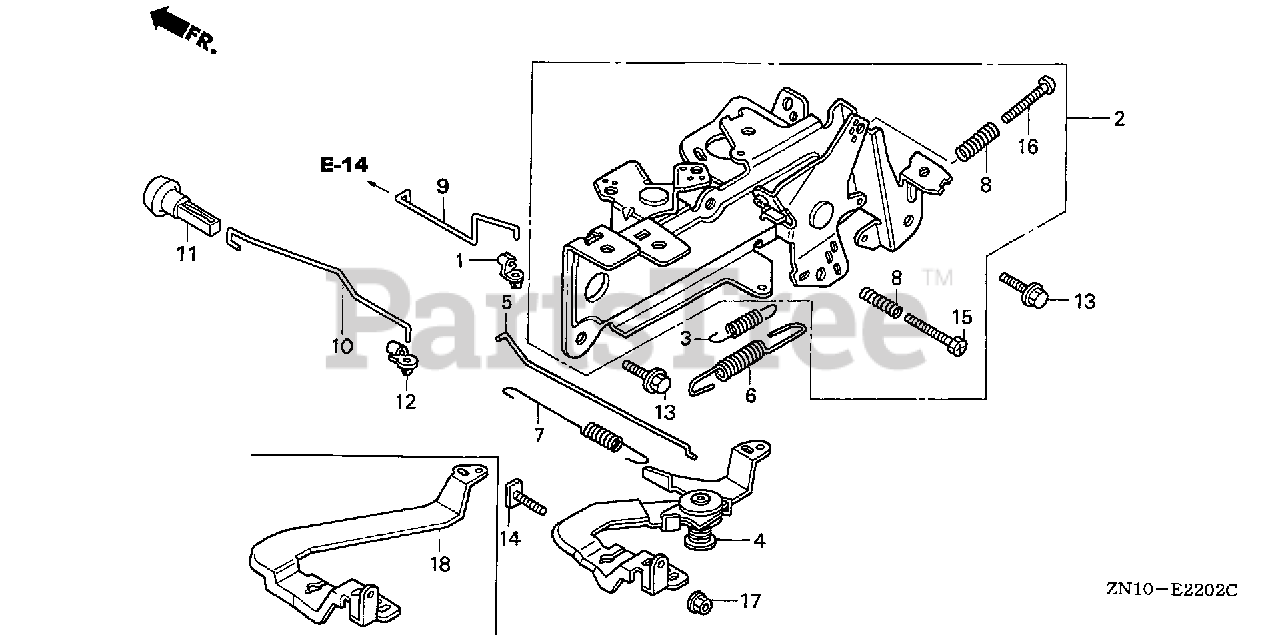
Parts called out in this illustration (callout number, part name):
1	JOINT, ROD
2	CONTROL ASSY. (AUTO THROTTLE)
3	SPRING, STARTER
4	ARM, GOVERNOR
5	ROD, GOVERNOR
6	SPRING, GOVERNOR (MANUAL)
7	SPRING, THROTTLE RETURN
8	SPRING, CONTROL ADJUSTING
9	ROD, CHOKE CONTROL
10	ROD, CHOKE KNOB
11	KNOB, CHOKE
12	BUSH, LINKAGE
13	BOLT, FLANGE (6X14) (CT200)
14	BOLT, GOVERNOR ARM
15	BOLT, RECESSED (5X25)
16	SCREW, PAN (5X35)
17	NUT, FLANGE (6MM)
